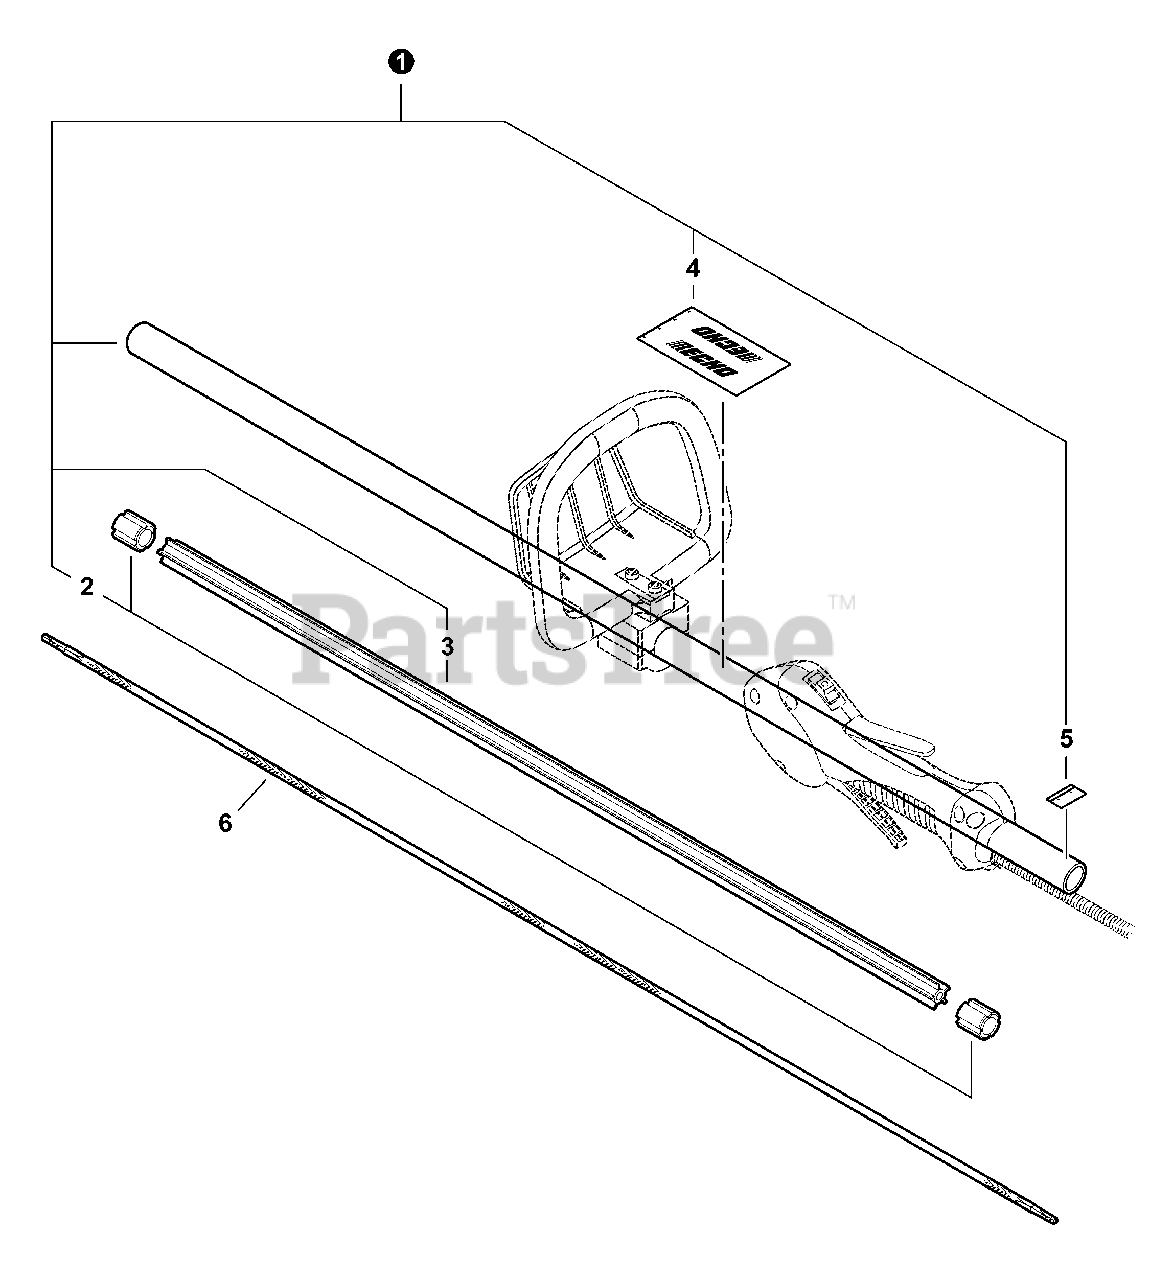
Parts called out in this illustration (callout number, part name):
1	MAIN PIPE ASSY
3	LINER - FLEXIBLE
4	LABEL - HANDLE LOCATION
5	LABEL - ALIGNMENT
6	DRIVESHAFT - FLEXIBLE
